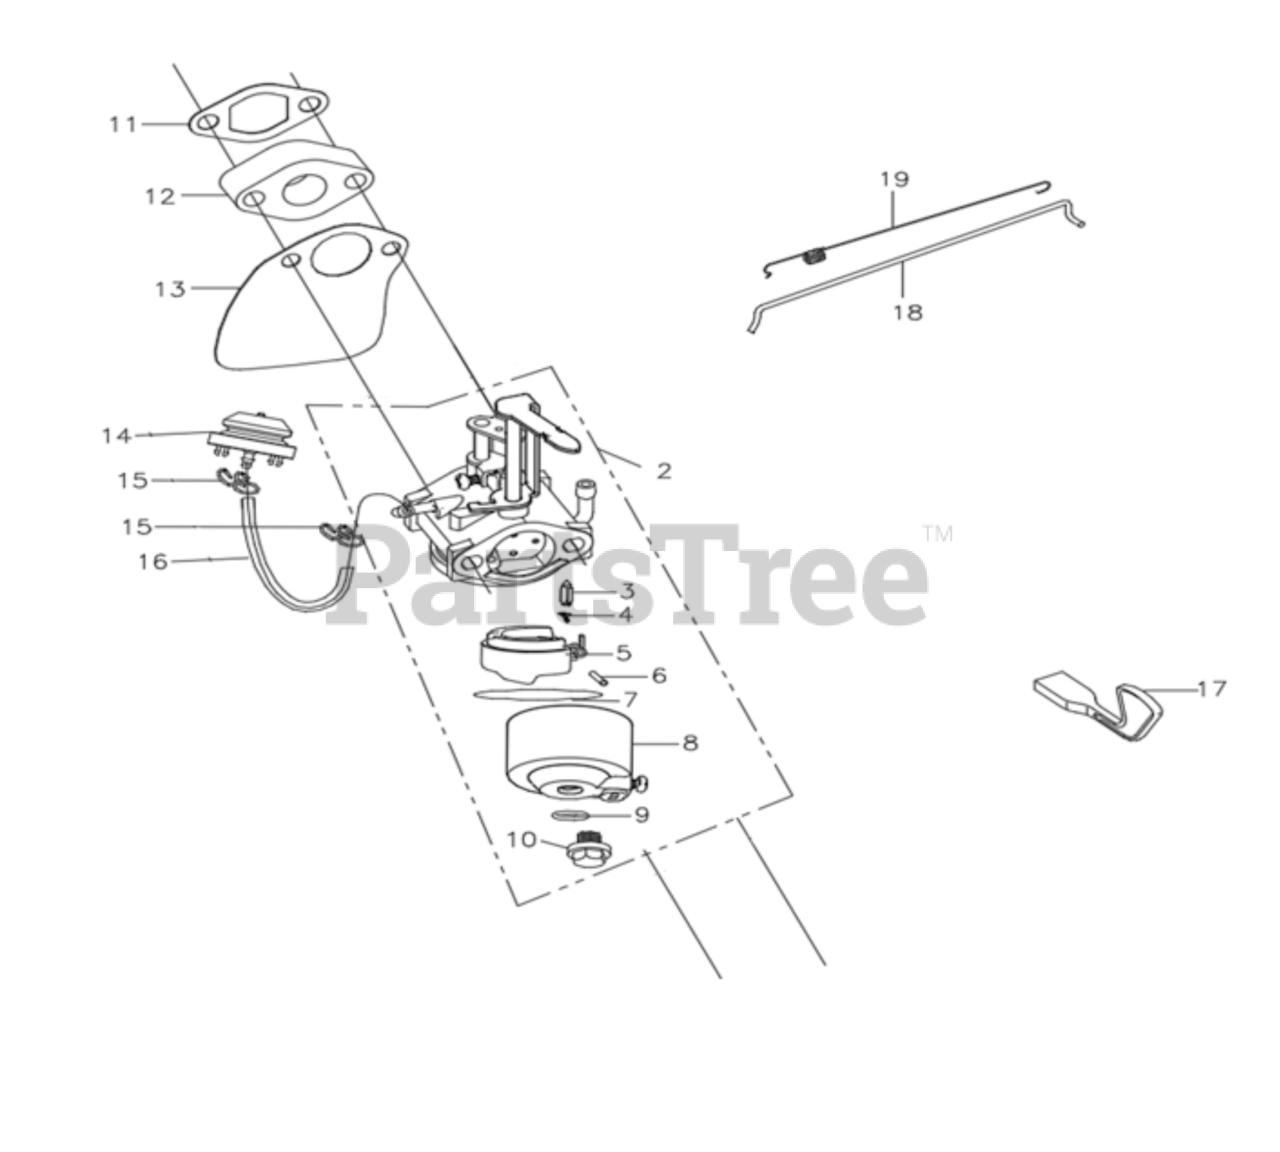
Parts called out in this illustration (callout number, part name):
2	Carburetor assembly
3	Needle valve
4	Compression spring
6	Float pin
7	float bath Seal ring
8	float bath
9	Seal ring
10	Hexagon bolt with flange
11	Carburetor gasket
12	Heat insulating pad for carburetor
13	Carburetor gasket
14	Starting primer bulb
15	Tube clip
16	Breather hose
17	Handle of carburetor choke valve
18	Throttle rod
19	throttle reset spring
